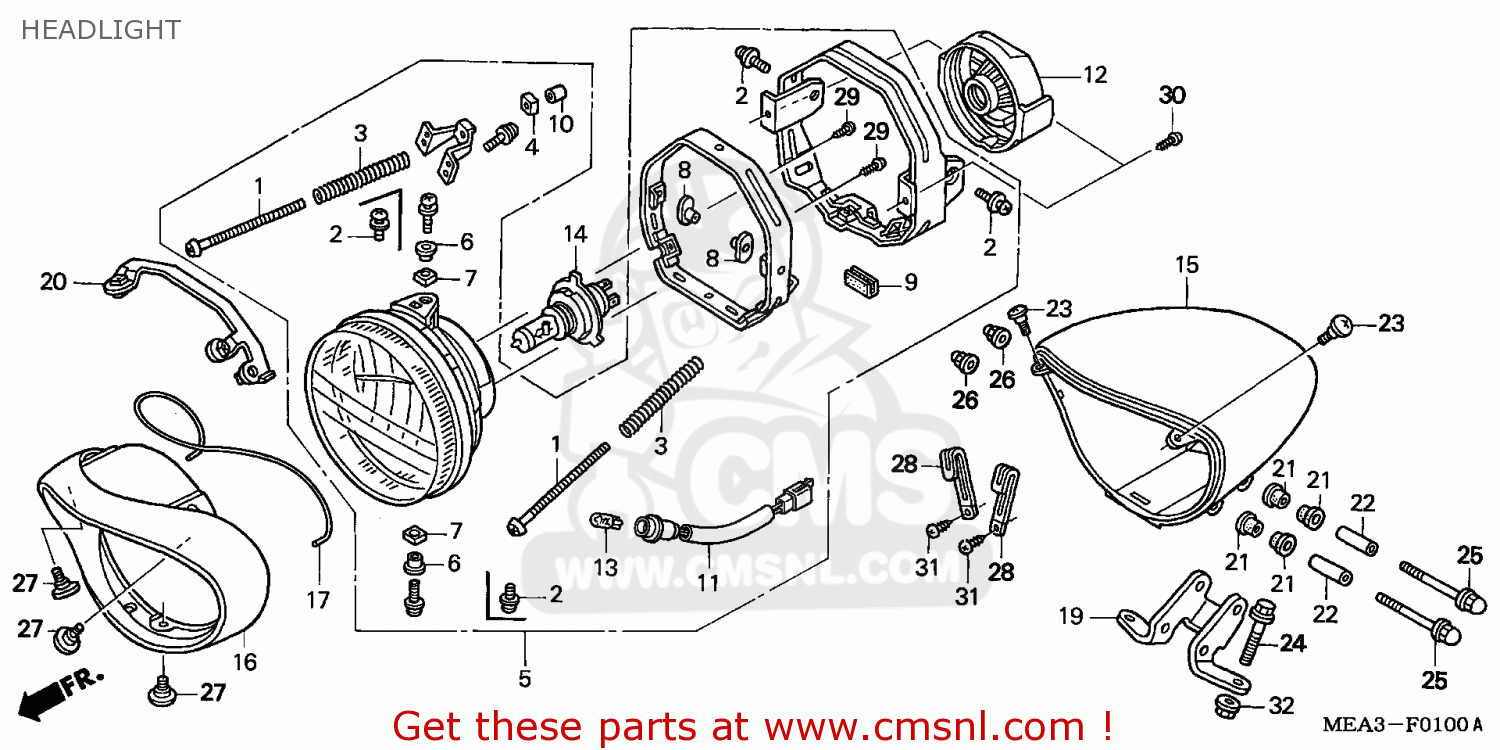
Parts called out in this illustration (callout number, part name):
1	SCREW,BEAM ADJUST
2	SCREW-WASH
3	SPRING,BEAM ADJUS
4	NOT,BEAM ADJ.
5	HEADLIGHT UNIT
6	SPACER
7	NUT,UNIT HOLDER
8	NUT,SPECIAL
9	WEAR RESISTANCETA
10	COVER,SCREW
12	COVER,RUBBER
14	BULB,HEAD LIGHT (
15	CASE,HEAD LIGHT
16	RIM,HEAD LIGHT
17	RUBBER,SPONGE
19	STAY,HEAD LIGHT
20	STAY,A HEAD LIGHT
21	MT.RUB.,HDLT.
22	COLLAR,HDLT.STAY
23	SCREW,SPECIAL,5MM
24	BOLT,FLANGE,8X28
25	BOLT,CAP 6MM
26	NUT,CAP,6MM
27	SCREW,SPECIAL 5X9
28	CLIP
29	SCREW,TAP.,4X12
30	SCREW,TAP.,4X12
31	SCREW,TAPPING,4X1
